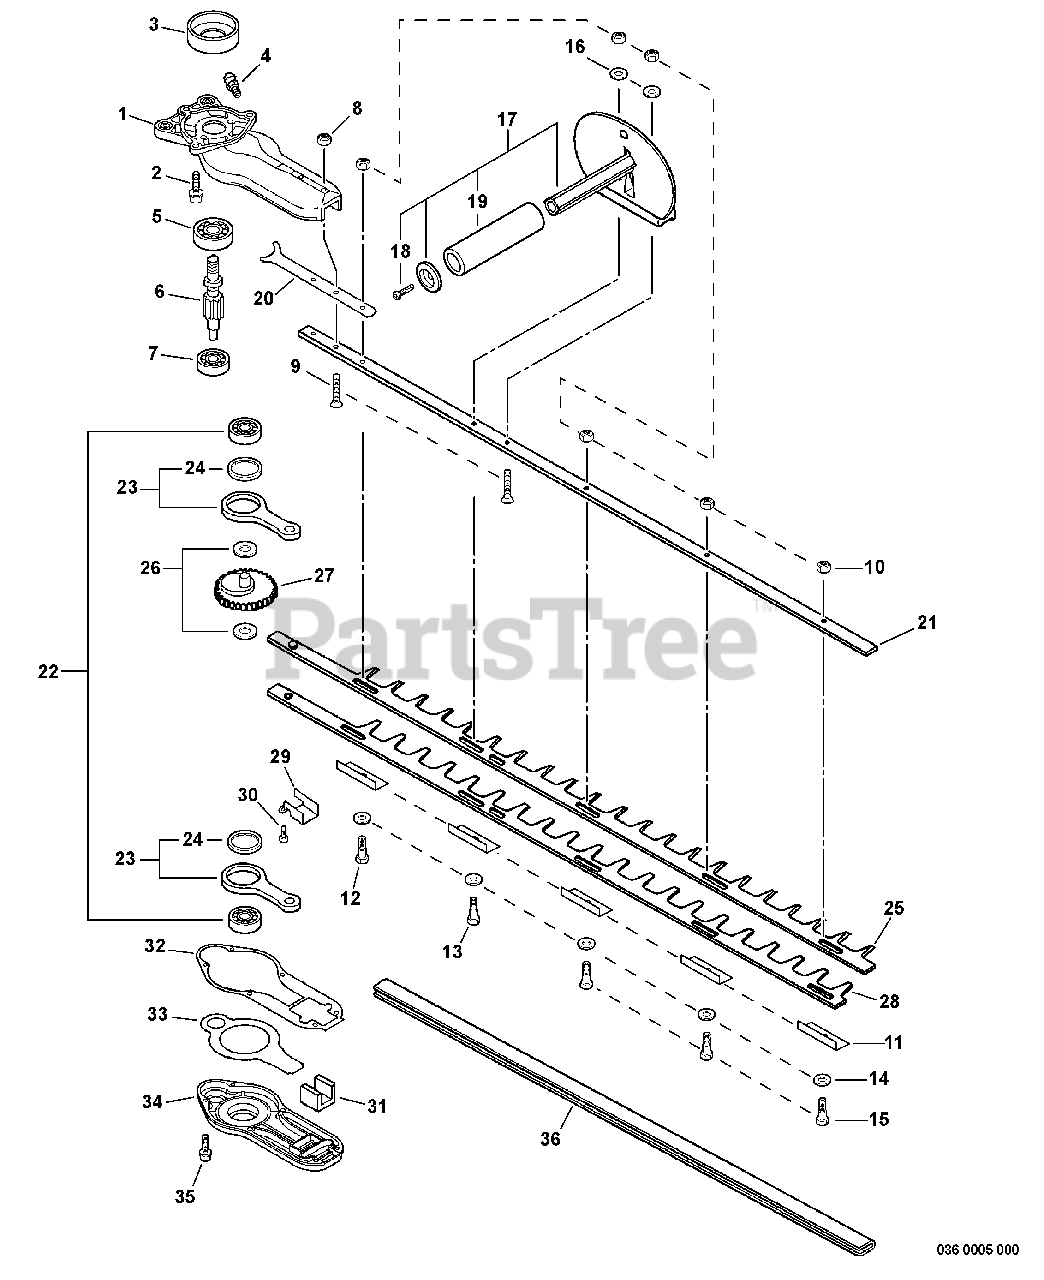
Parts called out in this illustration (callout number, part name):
1	CASE, GEAR - UPPER
2	SCREW - 6X18
3	DRUM, CLUTCH
4	FITTING, GREASE
5	BEARING, BALL - 6200
6	GEAR - SPUR
7	BEARING, BALL - 608ZZ
8	NUT - 6 -- FLANGE
9	SCREW - 6X30
10	LOCKNUT - 6
11	INSULATOR
12	BOLT - 6
16	WASHER - 6
17	HANDLE ASSY - FRONT
18	SCREW - 5X14
19	GRIP, HANDLE
21	SUPPORT, BLADE - 30" (76cm)
22	BEARING, BALL - 6200
23	ROD, CONNECTING
24	BEARING, NEEDLE
25	BLADE - 30" (76mm) -- UPPER
26	WASHER - 10
27	GEAR - SPUR
28	BLADE - 30" (76mm) -- LOWER
29	GUIDE, BLADE
30	SCREW - 4X16
32	GASKET, GEAR CASE
33	PLATE, GEAR CASE
34	CASE, GEAR - LOWER
35	SCREW - 4X16
36	COVER, BLADE
